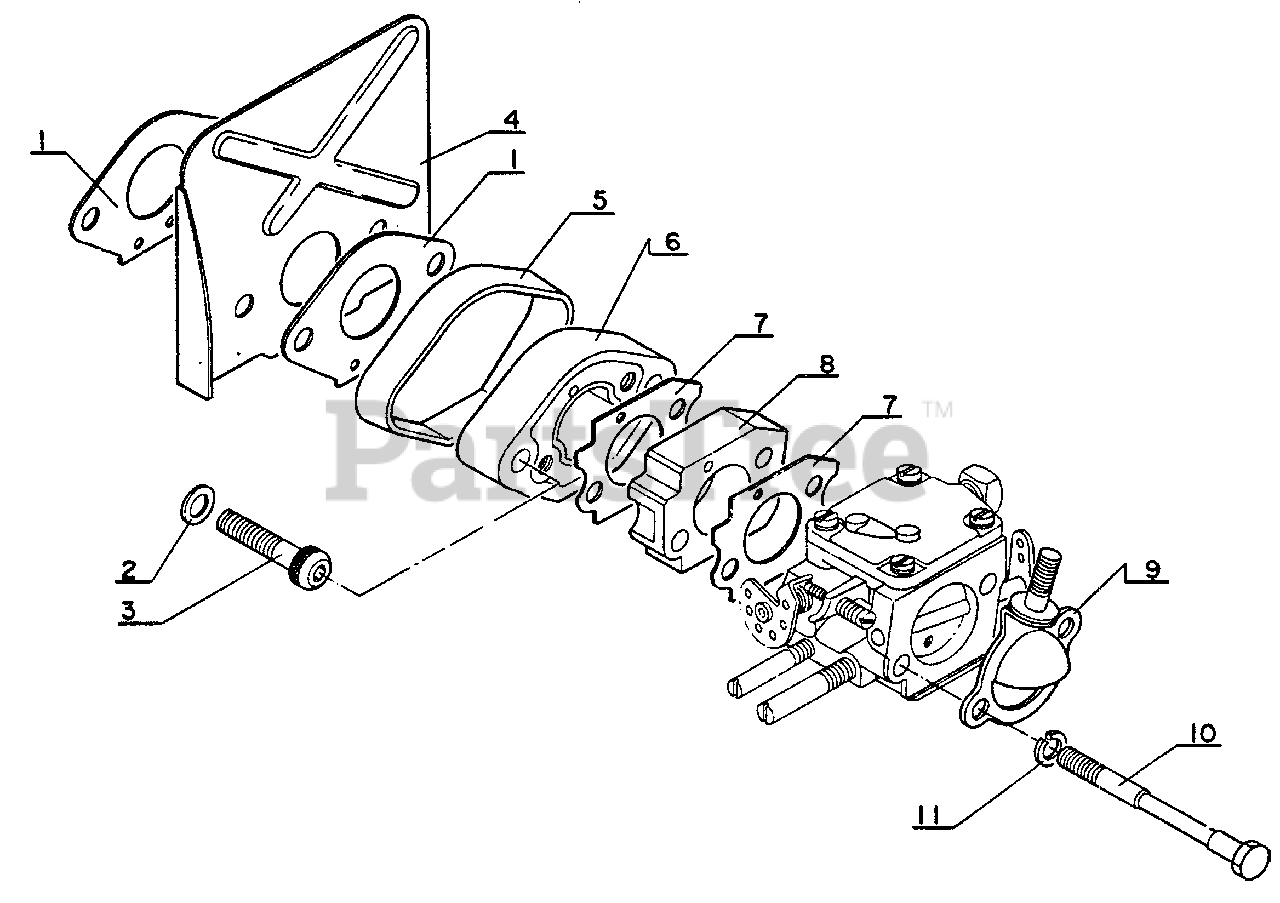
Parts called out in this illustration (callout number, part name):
3	BOLT - 6×28
4	PLATE, WIND PROOF
6	CASE, CARBURETOR
8	INSULATOR
9	PLATE, PREVENT
11	WASHER, SPRING 5
